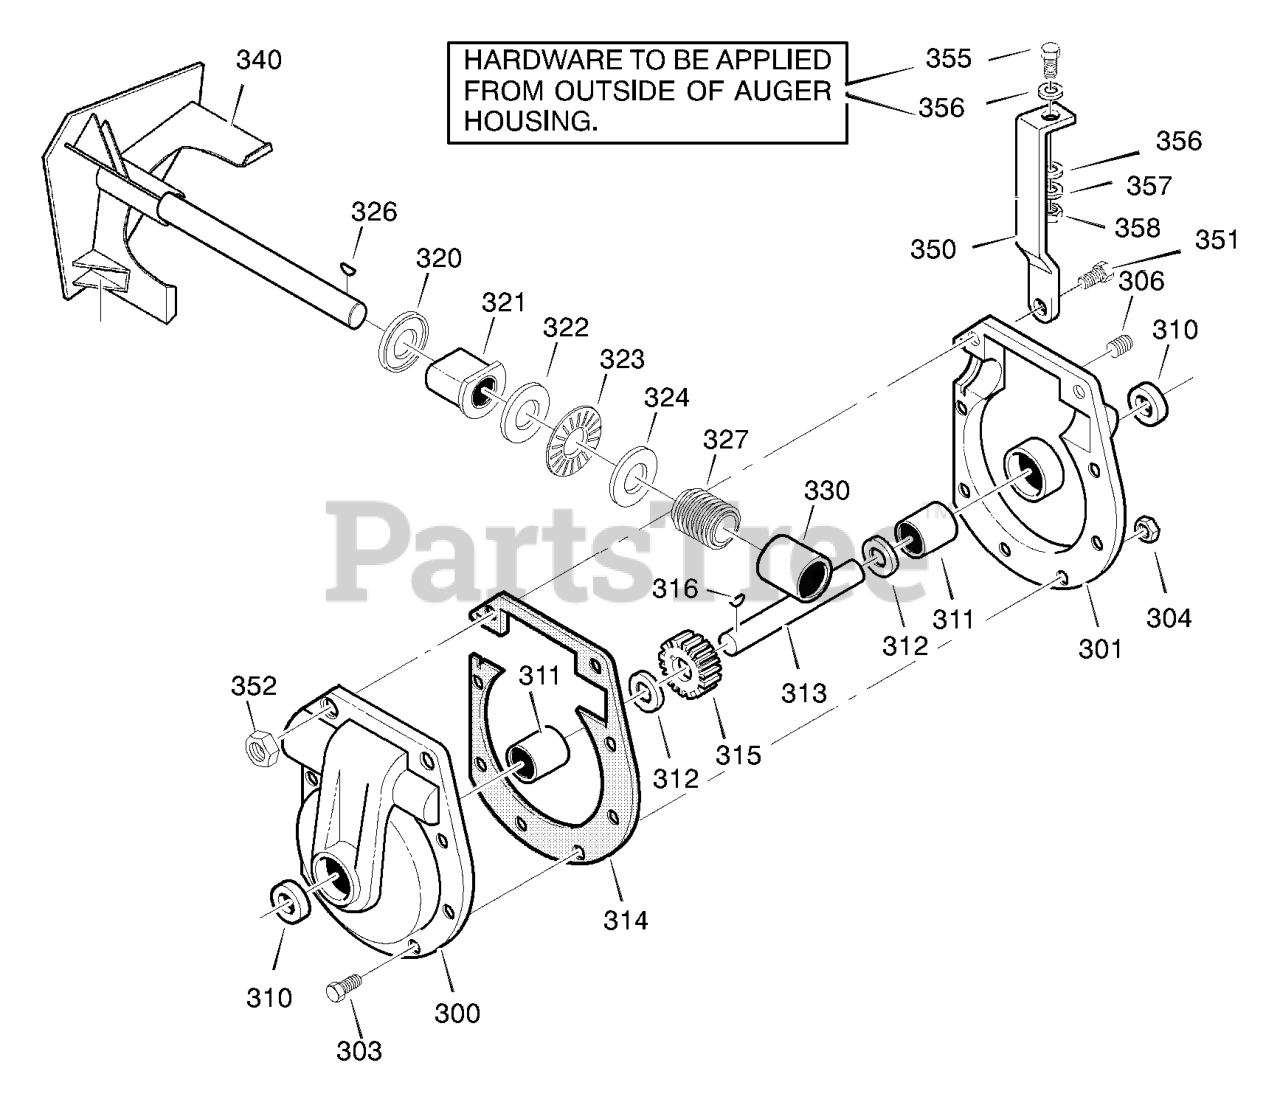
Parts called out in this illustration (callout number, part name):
300	CASE, GEAR, RH
301	CASE, GEAR, LH
303	SCREW,1/4-20X.75
304	NUT,1/4-20
305	NUT, 1/4-20 HEXKEPS
306	SCREW, 3/8-16 x 0.50
310	SEAL, OIL
311	BEARING, FL
312	WASHER, FLAT
313	SHAFT, AUGER OUTPUT
314	GASKET, GEAR BOX
315	WORM GEAR
316	KEY, WOODRUFF #61
320	BRNG, FL
321	SHAFT, AUGER INPUT
322	COLLAR, THRUST
323	PIN, SPRING
324	WASHER, FLAT
326	BRNG, FL
327	SEAL, OIL
330	BEARING
350	BRACE, GEAR BOX
351	SCREW, 5/16-24 x 1.75
352	NUT, HEX 5/16-24
355	SCREW, 5/16-18 x 1.75
356	WASHER, FLAT
357	WASHER, SPTLK
358	NUT, REGHEX 5/16-18
